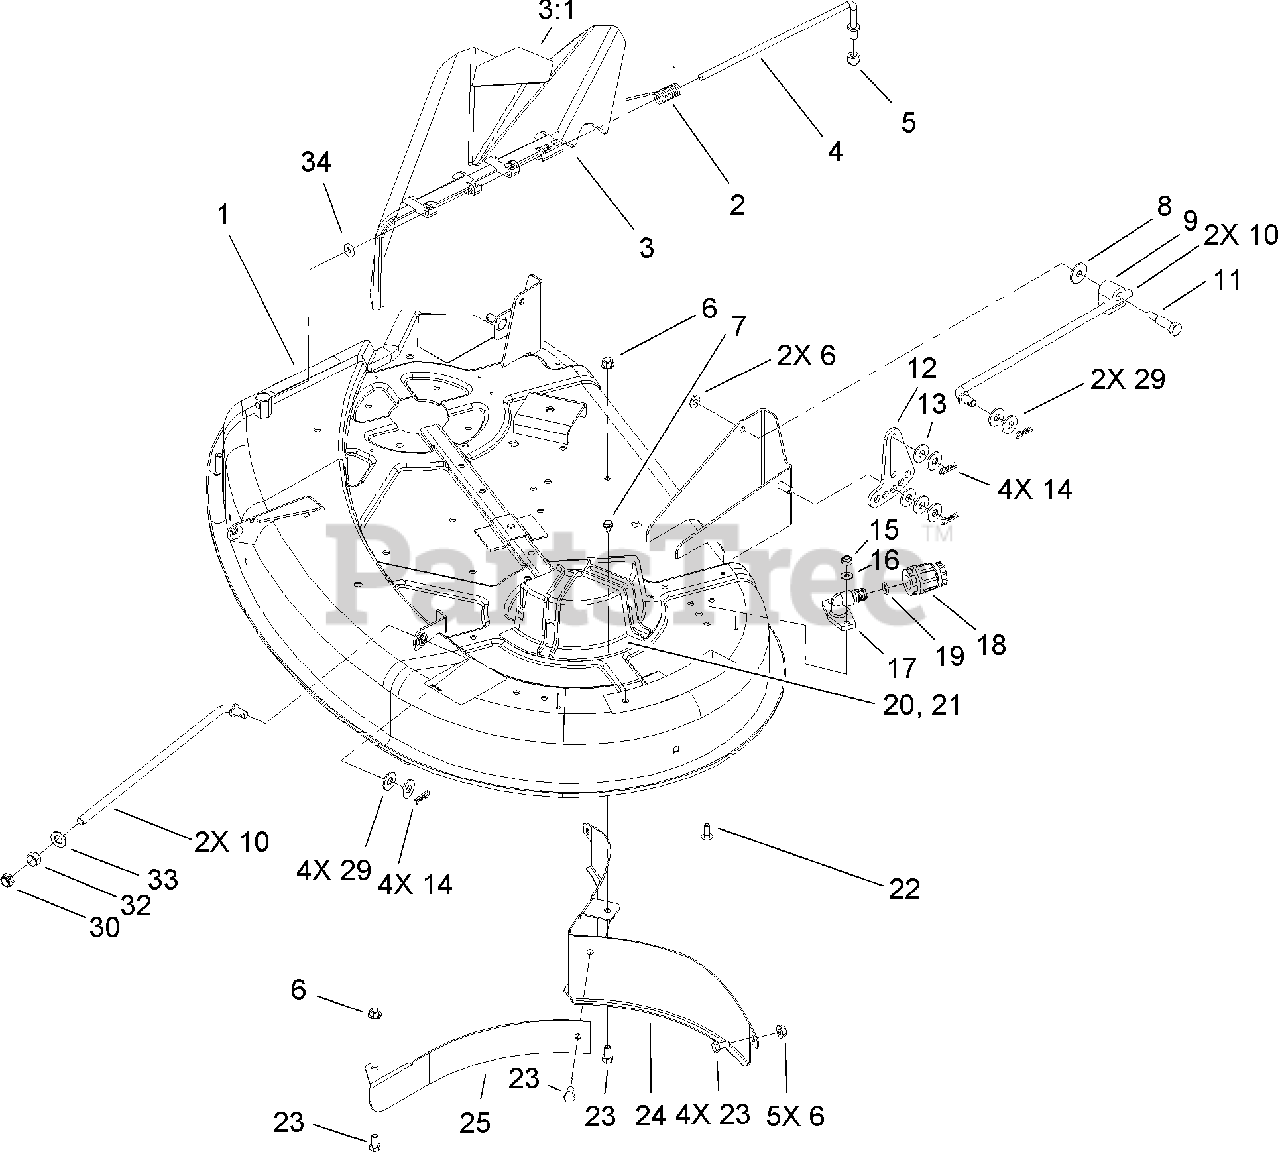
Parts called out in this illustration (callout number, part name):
3	DEFLECTOR ASM
3:1	DECAL-DANGER
4	ROD-PIVOT
5	NUT-LOCK, NI
8	WASHER-PIVOT
9	TRUNNION-HOC
10	ROD-HANGER
11	BOLT-SHOULDER
12	LINK-ADJUSTING, HOC
13	WASHER-HARDENED
14	PIN-HAIR
15	NUT-LOCK, NI
16	WASHER-FLAT
17	FITTING-WASHOUT
18	CONNECTOR-HOSE
20	LH BELT GUIDE-DECK
22	SCREW-CARR
23	SCREW-HH
24	BAFFLE-REAR
25	EXTENSION-BAFFLE
29	WASHER-FLAT
30	NUT-LOCK, NI
32	NUT-HEX
33	WASHER-FLAT
